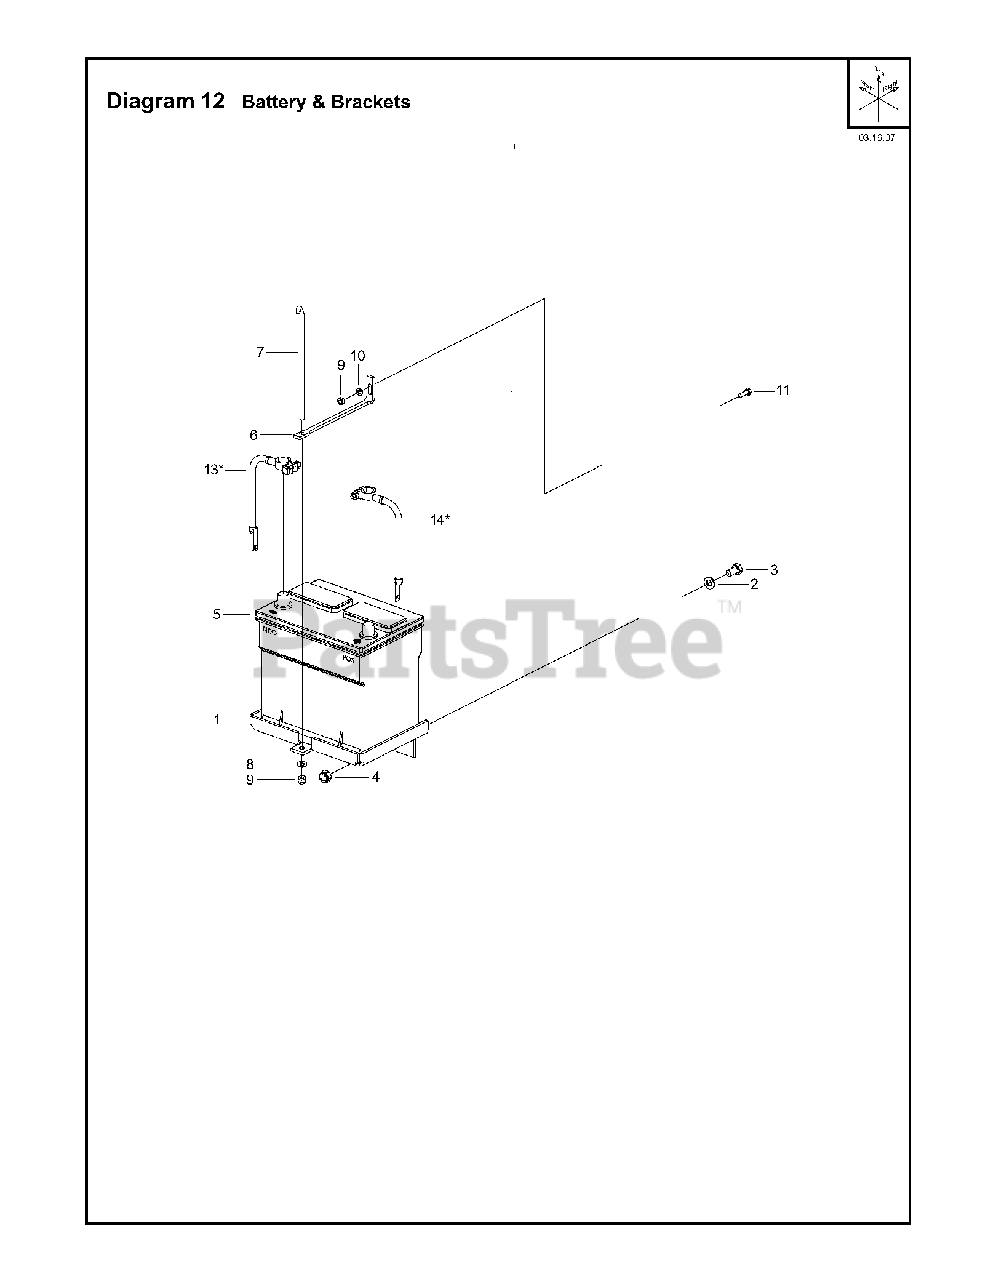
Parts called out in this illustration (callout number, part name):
3	HHCS. M10 x 1.5 x 20 DIN933 ZP
4	LOCKNUT. FIBER M10 DIN 985
6	BATTERY BRACKET. BLACK
7	J-BOLT: .25-20 x 9.0 Z/P
9	LOCKNUT. FIBER .25-20 Z/P
10	WASHER
11	GRIP HANDLE DLM
12	LOCKNUT. FIBER M6 DIN 985
13	CABLE
13	BATTERY CABLE #12-4
